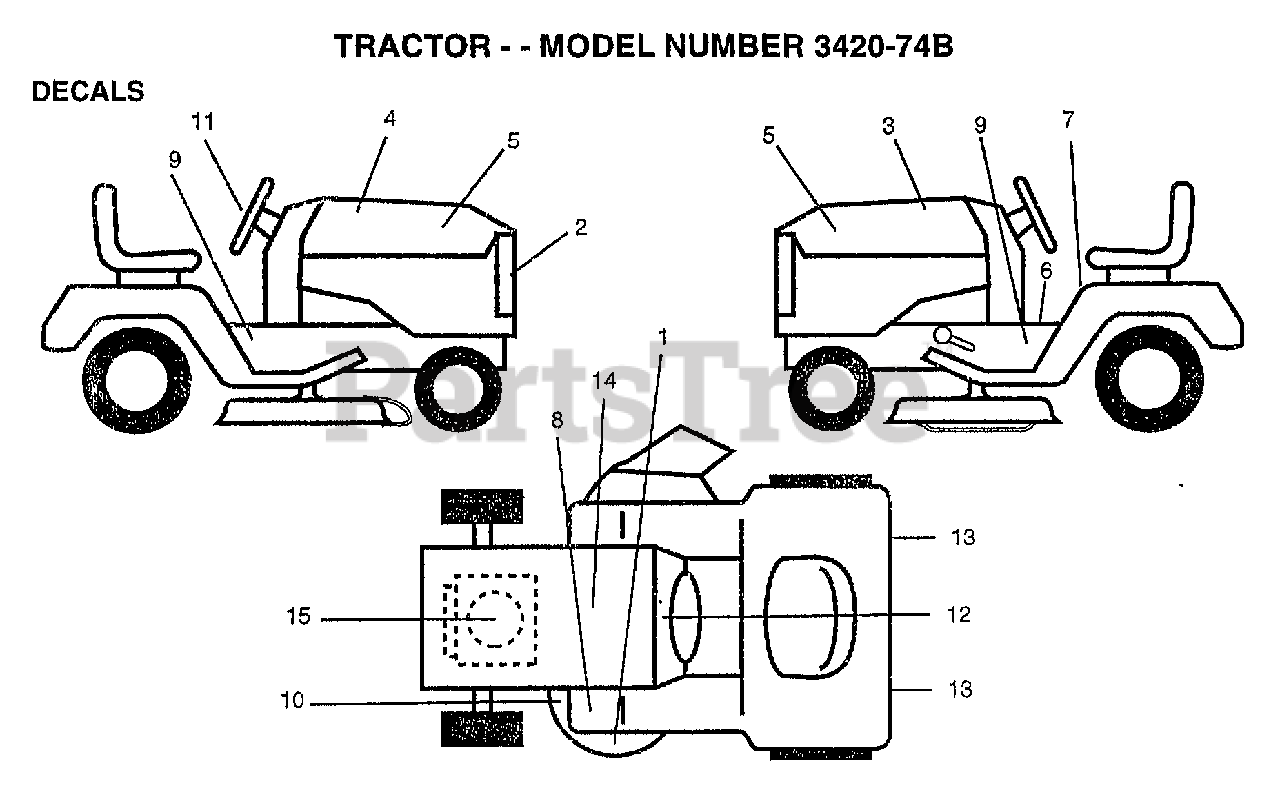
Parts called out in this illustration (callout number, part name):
2	GRILL DECAL
3	HOOD DECAL LH
5	NAMEPLATE LOGO
6	DECAL BRAK PARK
7	"DECAL DANGER,FEND"
9	DECAL.CHASSIS
10	DECAL
12	"DECAL-OPER,GEAR D"
13	REFLECTOR-TAIL YT
14	DECAL, BTRY DNGR/PSN
15	DECAL, HP ENGINE
